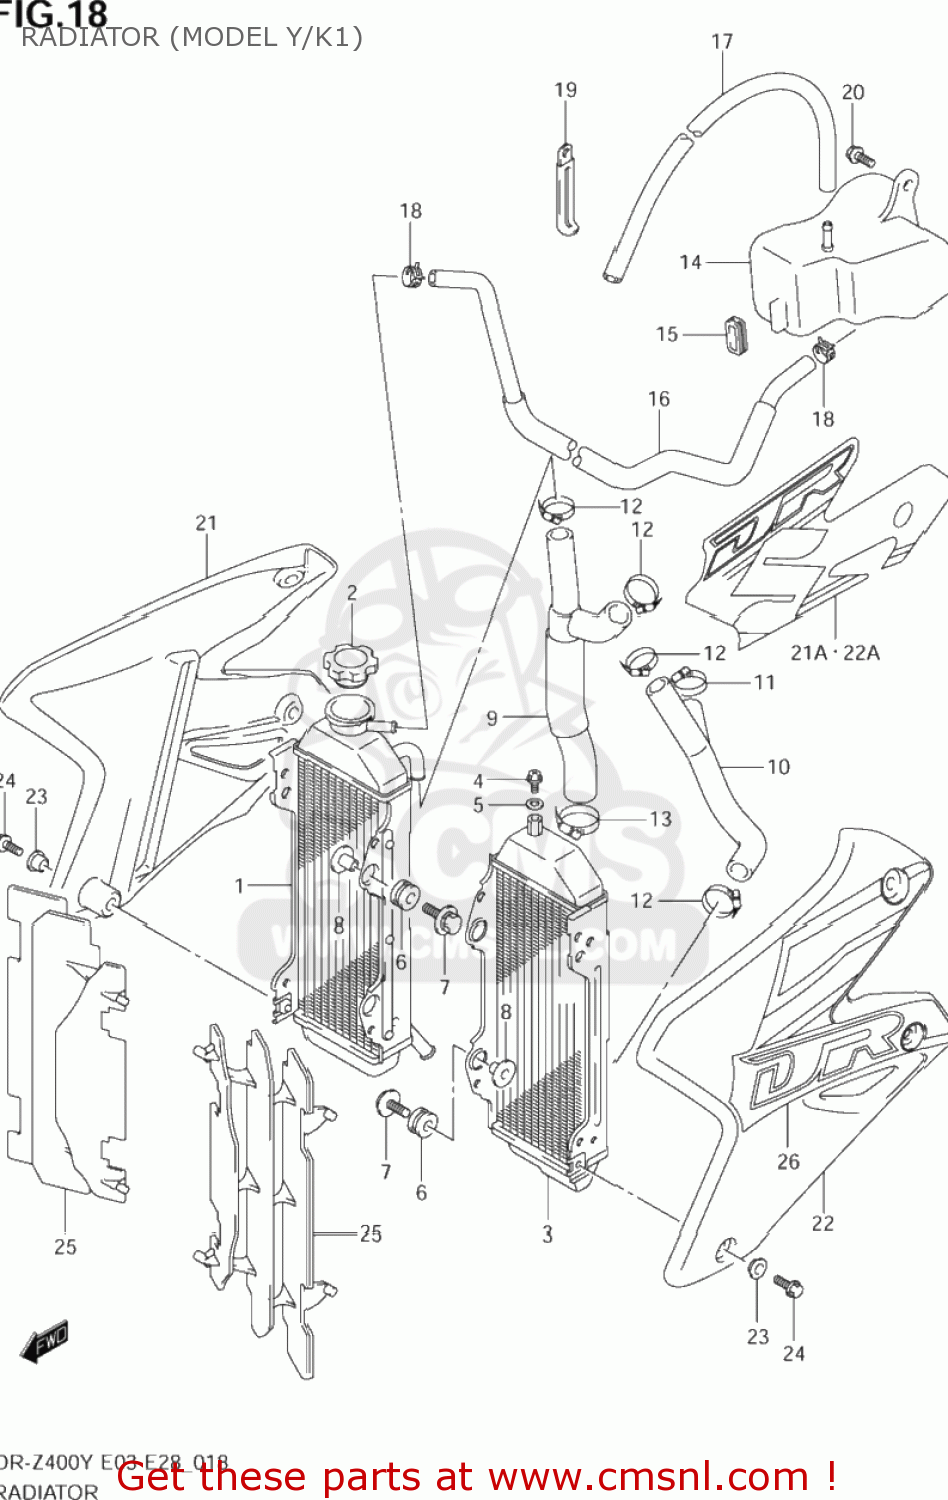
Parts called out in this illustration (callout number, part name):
1	RADIATOR,WATER,R
2	CAP,RADIATOR
3	RADIATOR,WATER,L
4	UNION BOLT,AIR VENT
5	GASKET(6.4X11.5X0.8) (NAS)
6	CUSHION,RADIATOR LWR
7	BOLT(6X25)
8	SPACER(6.5X10.5X14.1)
9	HOSE,RADIATOR INLET
10	HOSE,RADIATOR OUTLET
11	CLAMP
12	CLAMP
13	CLAMP
14	TANK,RESERVOIR
15	CUSHION,RESERVOIR TANK
16	HOSE,RESERVOIR TANK INLET
17	HOSE(5X9X2000)
18	CLIP
19	CLAMP(L:65)
20	BOLT
21	COVER,RADIATOR
21A	TAPE,RADIATOR COVER,R
22	COVER,RADIATOR
22A	TAPE,RADIATOR COVER,L
23	WASHER
24	BOLT
25	LOUVER,RADIATOR
26	TAPE,RADIATOR COVER,R
